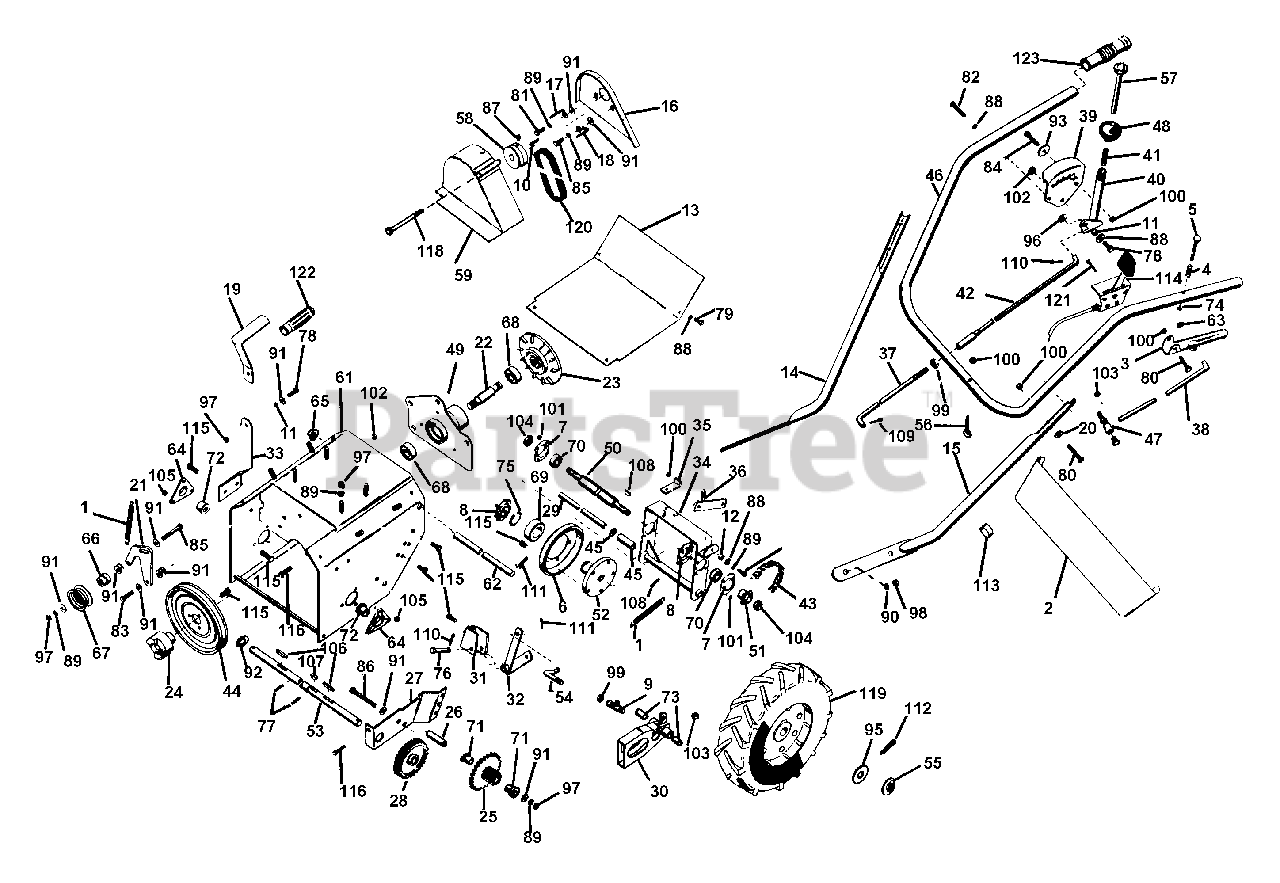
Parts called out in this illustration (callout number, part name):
1	SPRING
2	HANDLE BAR PANEL
3	CLUTCH HANDLE
4	SG-COMP ??X.44X?? WLD 10
5	CLUTCH LOCK PIN
6	FRICTION DISC
7	BEARING FLANGE
8	BEARING FLANGE
9	BALL JOINT
11	SPACER BUSHING .5 X .32 X .21
12	SPACER BUSHING .5 X .32 X .163
13	BOTTOM COV
14	R H LOWER HANDLE BAR
15	L H LOWER HANDLE BAR
16	INNER BELT GUARD
17	R H BELT FINGER
18	L H BELT FINGER
19	CLTCH LEVER
20	HANDLE BAR WASHER
21	IDLER ARM
22	SPINDLE
23	DRIVE PLATE
24	JAW COUPLING
25	PINION & SPROCKET
26	PINION STUB SHAFT
27	SUPPORT BRACKET
28	SPUR GEAR, FELLOWS 35T .750 ID
29	BRACKET PIN
30	SLIDING FORK
31	LEVER BRACKET
32	TRANSFER LEVER
33	CLTCH BRCKT
34	DISC BRCKT
35	NEUTRAL CATCH
36	THROWOUT LEVER
37	LOWER SHIFT ROD
38	CLTCH ROD
39	SHIFT QUADRANT
40	SHIFT HANDLE
41	SPRING
42	SHIFT ROD
43	ROLLER CHAIN
46	UPPER HANDLE BAR
47	BALL JOINT
48	SHIFT BALL
49	BEARING HOUSING
50	HEX SHAFT
51	9 TOOTH SPROCKET
52	FRICTION DISC HUB
53	AXLE SHAFT
54	CONNECTING LINK
55	HUB CAP
56	ROD HANGER EYEBOLT
57	SHIFT RELEASE HANDLE
58	ENGINE SHEAVE
59	OUTER BELT GUARD
60	CARB COV
61	TRACTOR FRAME
62	FORK SHFT
63	RATCHET PLATE
64	SUPPORT, BEARING
65	CAP, .50 ROD YWZC
66	SPCR, BRG .315X.50X.688X.281
67	IDLER
68	BRG-BALL .750X1.750X.50
69	BRG-BALL 1.25X2.18X.63
70	BRG-BALL .500X1.38X.437
71	BSHG-FLG .625X.750X.500X.875BR
72	BSHG-FLG .750X1.000X.625X1.250
73	BSHG-SLV .500X.625X.500 BR
74	RG-RTNG-EXT .250X.031
75	RG-RTNG-EXT 1.250X.050
76	CLEVIS PIN
77	PIN-ROLL .250X1.25
78	BLT-HEX .31-18X.63 PL GR 2
79	BLT-HEX .31-18X.63 PL GR 2
80	BLT-HEX .38-16X1.25 PL GR 2
81	BLT-HEX .38-16X1.25 PL GR 2
82	BLT-HEX .38-16X1.25 PL GR 2
83	BLT-HEX .38-16X1.50 PL GR2
84	BLT-HEX .44-14X1.25 PL GR2
85	BLT-HEX .44-14X1.25 PL GR2
86	BLT-HEX .44-14X1.25 PL GR2
87	SCR-SET .38-16X.50 SKHCUP OH
88	WSHR-LK .250X.077 HVY PL
89	WSHR-LK .312X.097 PL HVY
90	WSHR-LK .375X.115 HVY PL
91	WSHR-FL-STL .38X.875X.083 PL
92	WSHR-FL-STL .531X1.062X.095 PL
93	WSHR-FL-STL .531X1.062X.095 PL
94	BRG-NEEDLE .625X.812X.50
95	WSHR-FL-STL .755X2.000X.125
96	WSHR-FL-STL.406X.812X.065PL
97	NUT-JAM .375-16 PL
98	NUT-JAM .375-16 PL
99	NUT-HEX .312-24 PL
100	NUT-LK-CTR .250-20 PL
101	NUT-LK TOP 10-24 PL
102	NUT-LK .312-18 GR A PL
103	NUT-LK-CTR .312-24 PL
104	NUT-LK-CTR .50-20 PL
105	NUT-LK-FLG .250-20 PL
106	KEY-WDRF .188X.875X.375 SAE11
107	KEY-WDRF .188X.875X.375 SAE11
108	KEY-WDRF .188X.875X.375 SAE11
109	PIN-COTR .09X.75 PL
110	PIN-COTR .12X1.0 PL
111	PIN-COTR .09X.75 PL
112	PIN-COTR .09X.75 PL
113	THROTTLE CONTROL
114	THROTTLE CONTROL
115	BLT-SERHFWH .31-18X.50 PL
116	BLT-SCRHFWH .38-16X.50 PL
117	SCR-SLTR-SERNK .25-20X.62 PL
118	BLT-HFWH .31-24X3.62 PL
120	V-BELT, 4L-WRAPPED
121	SCR-TAP 10-12X.50 CRPH PL A
123	GRIP
124	DISCHARGE CAUTION LABEL
125	DISCHARGE CAUTION LABEL
126	DISCHARGE CAUTION LABEL
127	DISCHARGE CAUTION LABEL
128	MOWER IN-OUT LABEL
